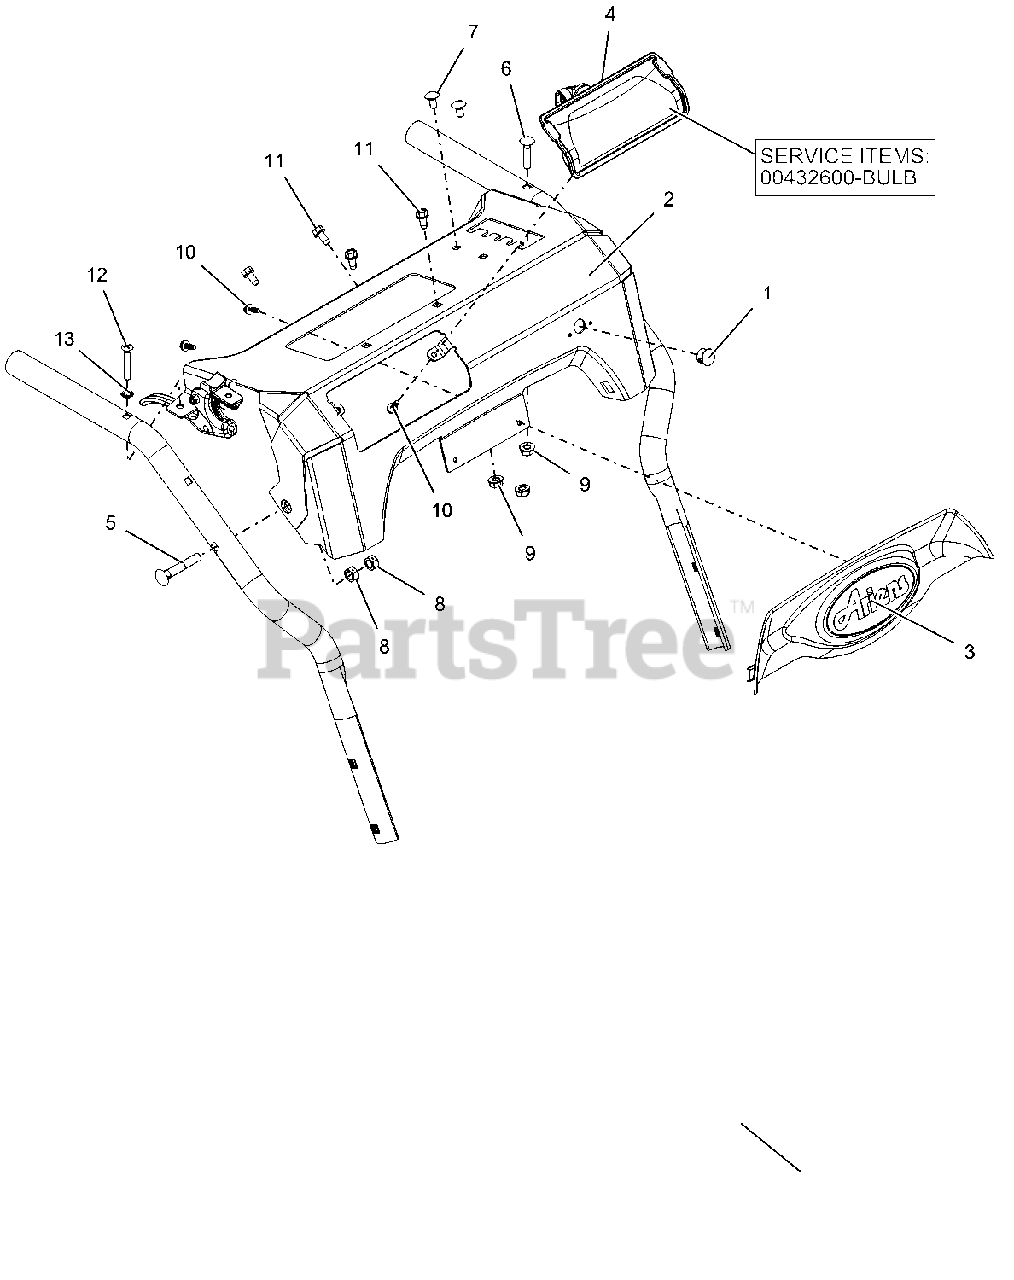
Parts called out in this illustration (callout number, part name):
1	HOLE PLUG, PLASTIC .56 HOLE
2	CONTROL PANEL W/DECAL, CMPT TK
3	BEZEL, DASH-ARIENS SM DASH
4	HEADLIGHT ASY, HALO 20W 2SHOT
5	BLT-RDHDXLSQNK .31-18X2.0 G5YZ
6	BLT-RDHDXLSQNK.25-20X1.25 G5ZC
7	@BLT-RDHDSQNK .25-20X.50 G5YZ
8	@NUT-LK-CTR .31-18 YWZC
9	@NUT-LK-TOP-FLG .25-20 YWZC
10	SCR-TAP #10X.50 BOSS INDHXHD
11	SCR-TAP .25-20X.50 HWH TR YWZ
12	SCR-MCH .25-20X1.50 OVAL HD
13	WSHR-LK-INT .250 TH TYA
14	BULB, LIGHT-HALOGEN 20W
